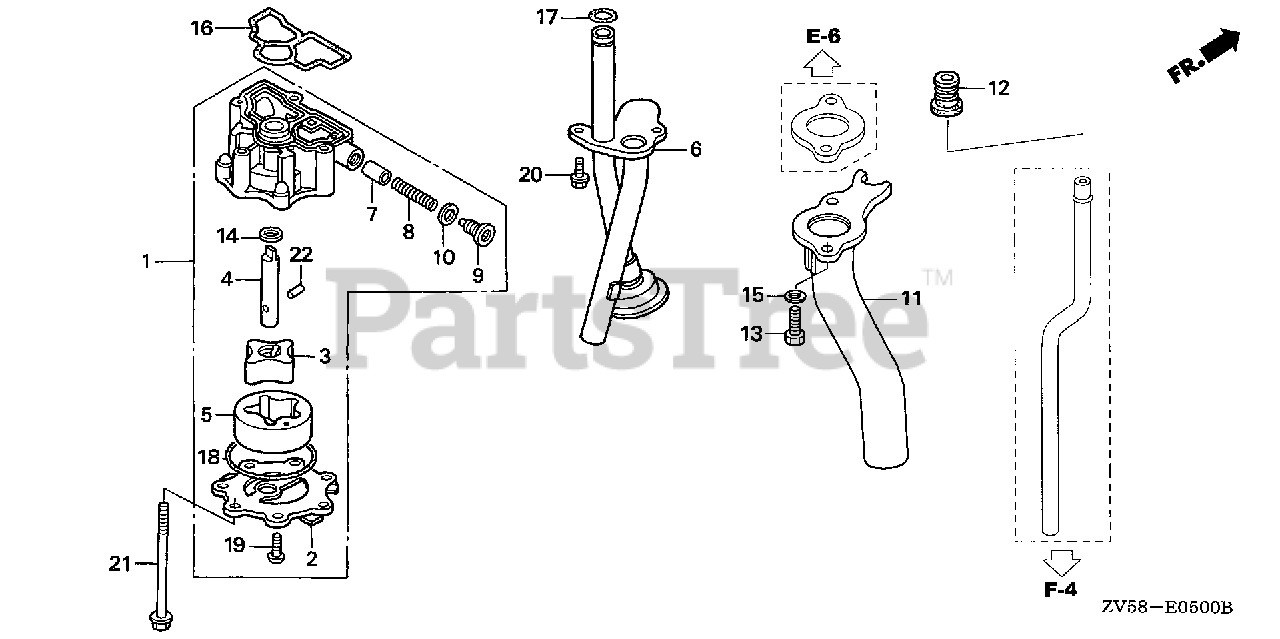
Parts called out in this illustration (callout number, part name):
1	PUMP ASSY., OIL
2	COVER, OIL PUMP
3	ROTOR (INNER)
4	SHAFT, OIL PUMP
5	ROTOR A (OUTER)
6	STRAINER, OIL
7	VALVE, RELIEF
8	SPRING, RELIEF VALVE
9	BOLT, SEALING (14MM)
10	WASHER, SEALING (14MM)
12	GROMMET, WATER TUBE
13	BOLT, HEX. (8X25)
14	WASHER, THRUST (13MM)
15	WASHER, PLAIN (8MM)
16	O-RING, PUMP COVER
17	O-RING (13.8X2.5)
18	O-RING (54X2.4) (ARAI)
19	SCREW, PAN (6X16)
20	BOLT, FLANGE (6X16)
21	BOLT, FLANGE (6X55)
22	ROLLER (5X17.8)
